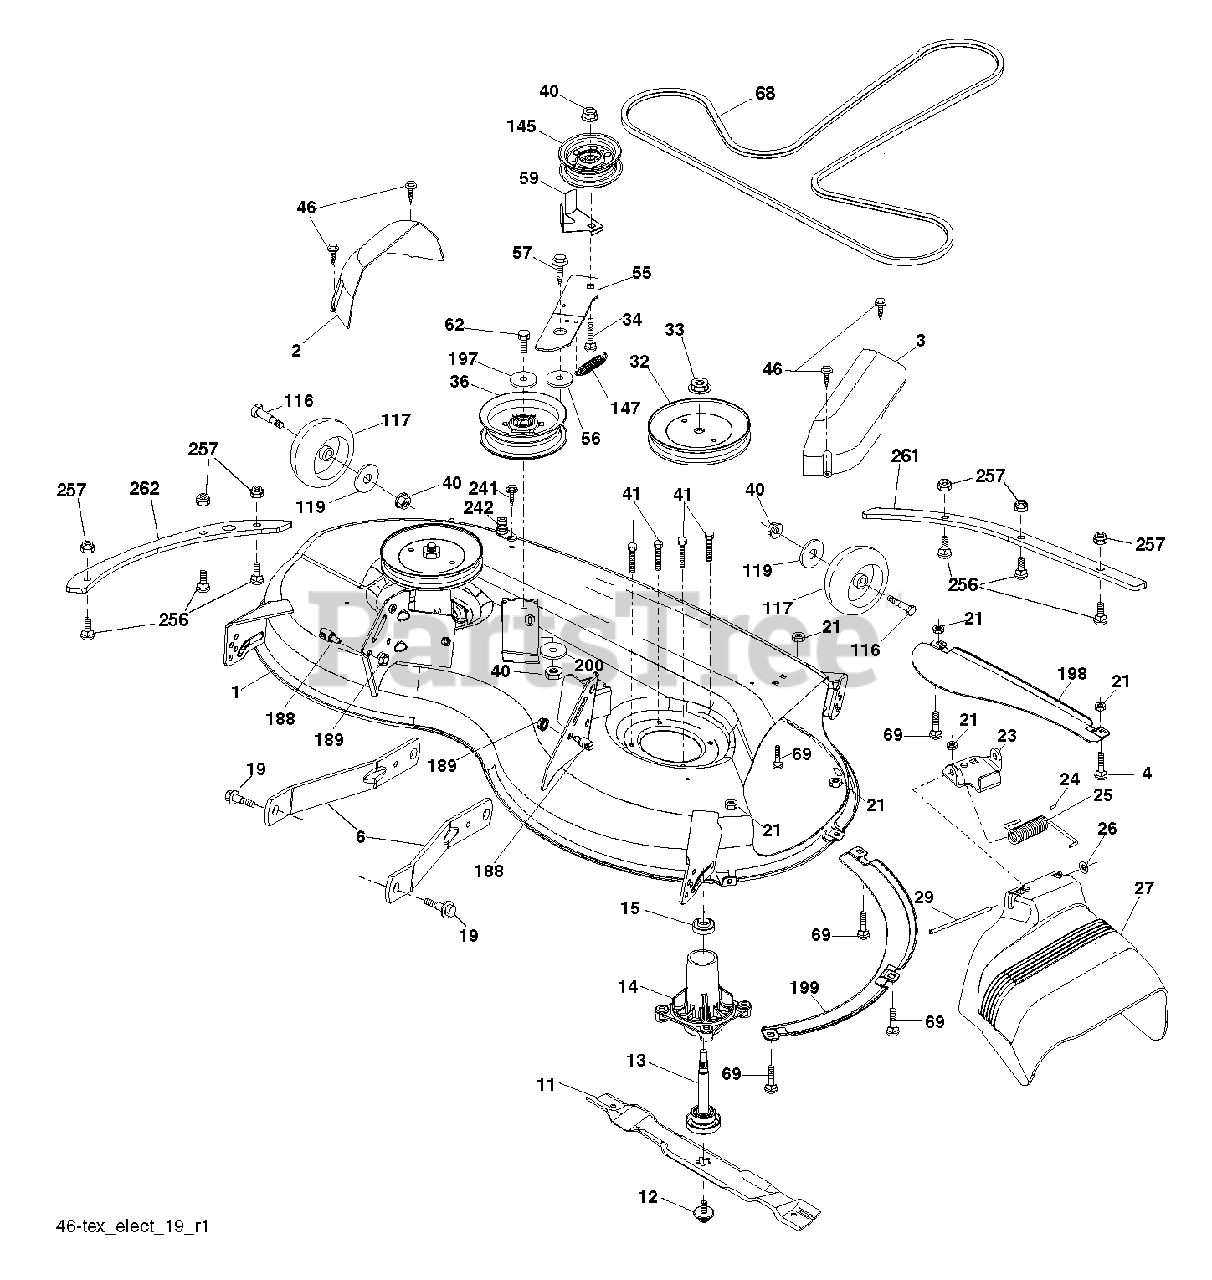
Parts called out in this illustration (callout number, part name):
1	Mower Deck Kit, 46"
2	COVER.MANDREL.LH.46"
3	COVER.MANDREL.RH.46"
4	BOLT
6	ARM.SUSPENSION.MOWER.R
11	BLADE.MOWER.46".HI.LIFT
12	SCREW.SEMS.7/16-20X1.HEX.HEAD
13	SHAFT ASM.MNDRL.N/GREASEABLE
14	HOUSING.MANDREL.4PT.
15	BEARING.MANDREL.TOP.EXTENDED
19	BOLT.SHOULDER
21	LOCKNUT
23	BRKT.DEFLECTOR.38"2005+
24	CAP-SLEEVE LT
25	SPRING.TORSION.DEFLECT
26	NUT PUSH M
27	SHIELD.DEFLECTOR.MOWER.46"BLAC
29	ROD.HINGE
32	PULLEY.MANDREL.5.438.PD
33	NUT.FLANGE.LOCK.TOP
34	BOLT.3/8-16X1.50
36	PULLEY.IDLER.2006
40	NUT LOCK FLG 3/8-16 UNC
41	BOLT.HEX.WASHR.HED.313-18X1.19
46	SCREW.1/4-20X5/8
55	IDLER.ARM
56	SPACER.RETAINER
57	SCREW 3/8-16X1
59	GUARD, BELT
62	BOLT-HEX EAK
68	V-BELT
69	BOLT
116	BOLT.SHOULDER.3/8-16X3-5/8.
117	WHEEL. GUAGE RALLY
119	WASHER
145	PULLEY.IDLER.48"PRIMARY
147	SPRING.MOWER.DRIVE.ELECTRIC
188	STUD.FASTNER.W/ANTI-ROTATE
189	NUT LOCK HEX FLANGE 5/16-18
197	WASHER
198	BAFFLE CENTER FRONT
199	BAFFLE FRONT RH
200	WASHER.13/32 X 1 X 1/2.11GUARD
241	SCREW.TT.#10-32X.5.3/8.FLANGE
242	PORT.WASHOUT
256	RHSNB, 1/4-20 X 1, GR5
257	NUT T
261	Deck Reinforcement Plate, 46 F
262	PLATE.REINF.DECK.46.S
